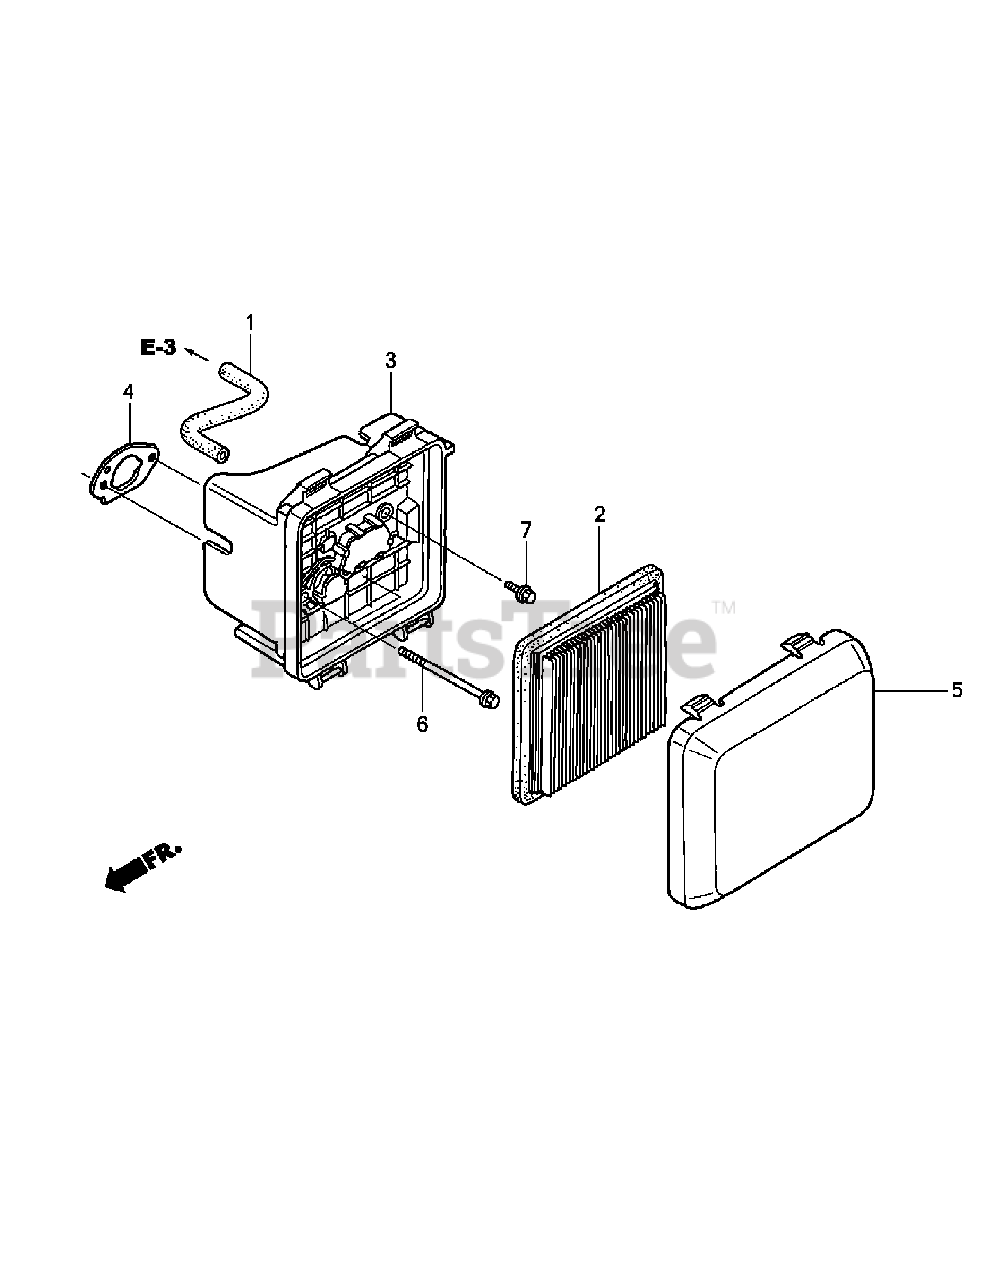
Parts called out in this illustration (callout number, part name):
1	Breather Tube
2	Air Cleaner Element
3	Air Cleaner Case Assembly
4	Air Cleaner Gasket
5	Air Cleaner Cover
6	Flange Bolt, 6 x 85
